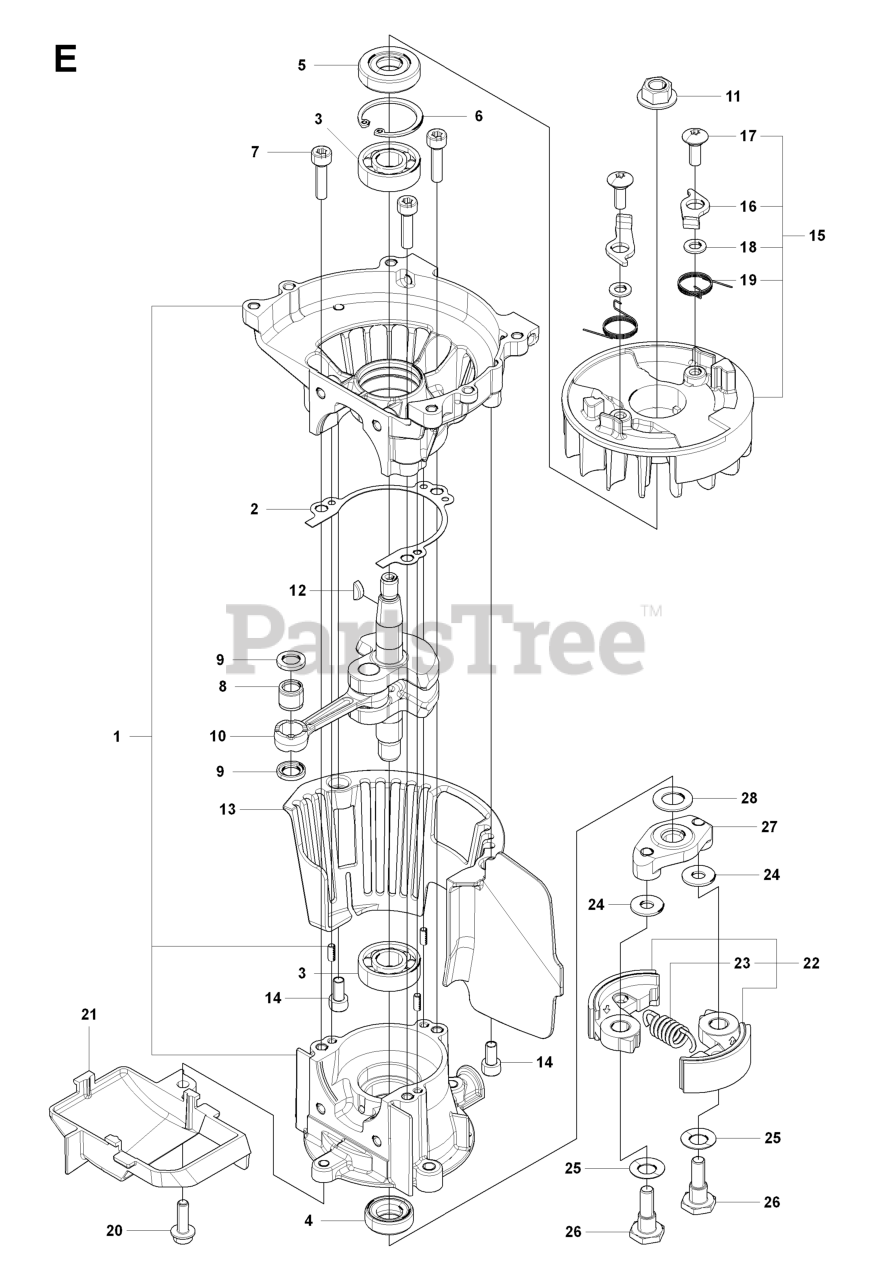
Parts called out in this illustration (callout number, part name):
1	CRANKCASE COMP
2	GASKET, CASE
4	SEAL
7	RP BOLT TORX M5XL20 T27
9	RP WASHER
10	CRANKSHAFT COMP
11	NUT M8XP1.0
14	BOLT TORX M5XL10 T27
15	ROTOR ASSY
18	WASHER 5X10X10
20	BOLT TORX
27	PLATE CLUTCH
